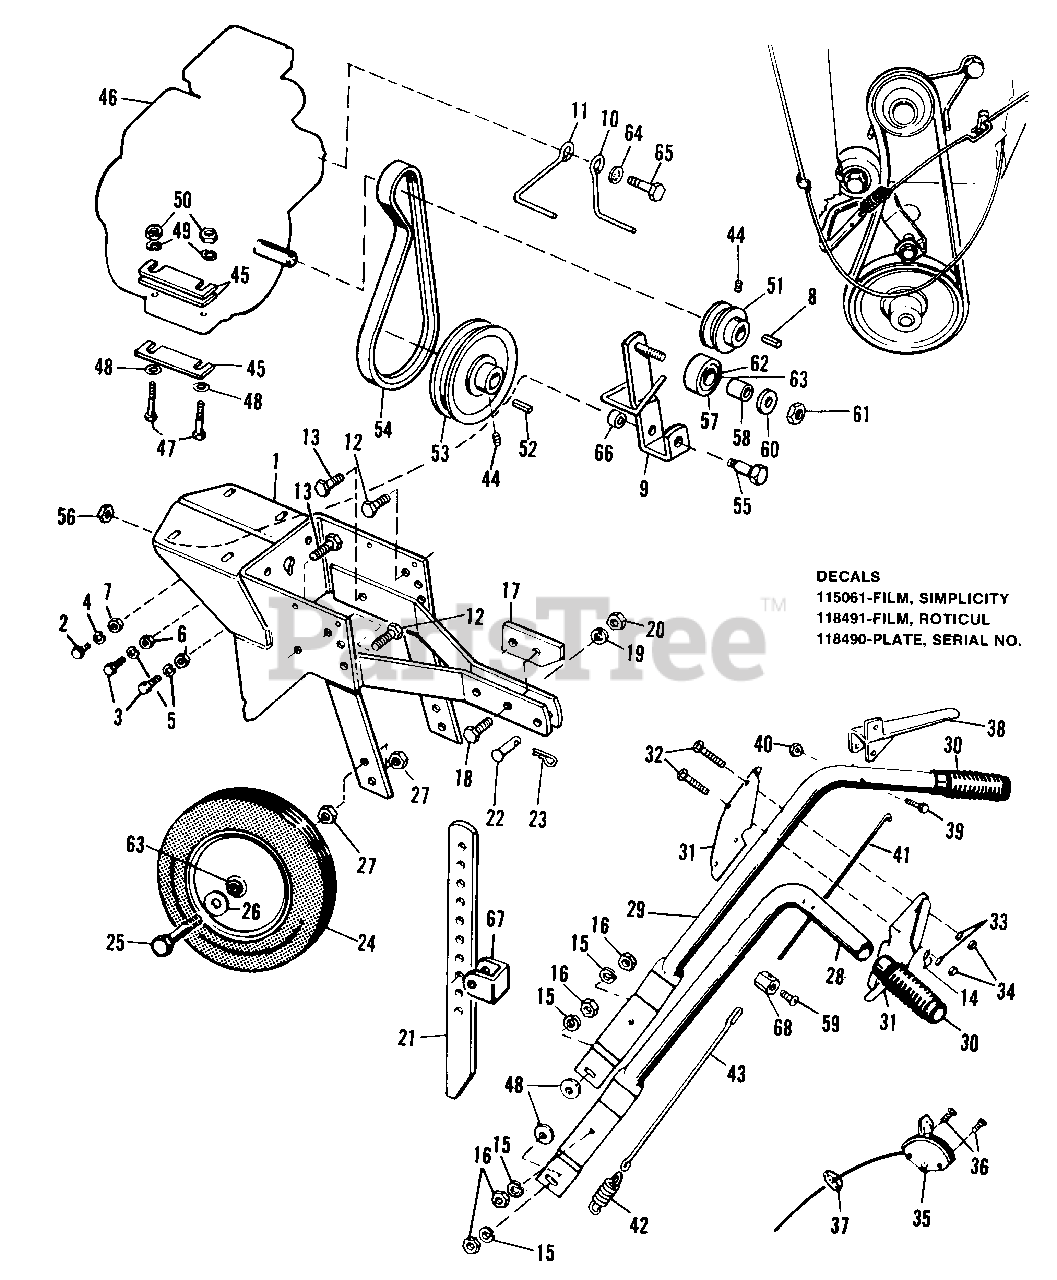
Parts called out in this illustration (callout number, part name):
1	BODY ASSY
2	CAPSCREW, Hex, 3/8-16 x 3/4
3	CAPSCREW, Hex, 7/16-20 x 1-1/4
3	CAPSCREW, Hex, 3/8-16 x 1/4
4	LOCKWASHER, 3/8
5	LOCKWASHER, 3/8
6	NUT, Hex, Full, 7/16-20
7	NUT, Hex, Full, 3/8-16
9	LEVER ASSY, Idler
11	STOP, Belt
12	CAPSCREW, Hex, 3/8-16 x 7/8
13	CAPSCREW, hex, 3/8-16 x 1-1/4
15	LOCKWASHER, 3/8
16	NUT, Hex, Full, 3/8-16
17	PLATE, Stop
18	CAPSCREW, Hex, 3/8-16 x 1-1/2
19	LOCKWASHER, 3/8
20	NUT, Hex, Full, 3/8-16
21	BAR, Depth
23	CLIP, Spring
24	WHEEL & TIRE ASSY
25	CAPSCREW, Hex, 1/2-13 x 3
26	WASHER, Plain, 1/2
27	NUT, Hex, Jam, 1/2-13
28	HANDLE, L.H.
29	HANDLE, R.H.
30	GRIP, Handle
31	COVER, Handle, Upper
32	CAPSCREW, Hex, 1/4-20 x 1-1/2
33	LOCKWASHER, 1/4
34	NUT, Hex, Full, 1/4-20
35	THROTTLE ASSY, Control
36	SCREW, Self-Tapping, #10-24 x 1-1/4
37	CLIP, Cable
38	GRIP, Clutch
39	CAPSCREW, Hex, 1/4-20 x 1-1/2
40	NUT, Hex, Full Lock, 1/4-20
41	EXTENSION, Spring
43	WIRE, Ext.
44	SETSCREW, 5/16-18 x 5/16
47	CAPSCREW, Hex, 5/16-18 x 2
48	WASHER, Plain, 5/16
49	LOCKWASHER, 5/16
50	NUT, Hex, Full, 5/16-18
51	PULLEY, Engine
53	PULLEY, Driven
55	BOLT, Pivot
56	NUT, Special, Whiz-Lock
57	PULLEY ASSY, Idler
59	SCREW, Rd. Hd., #10-24 x 3/8
60	WASHER, Plain, 5/16
61	NUT, Hex, Lock, 3/8-16
64	LOCKWASHER, 1/2
65	CAPSCREW, Hex, 1/2-20 x 1
68	CLAMP, Wire
